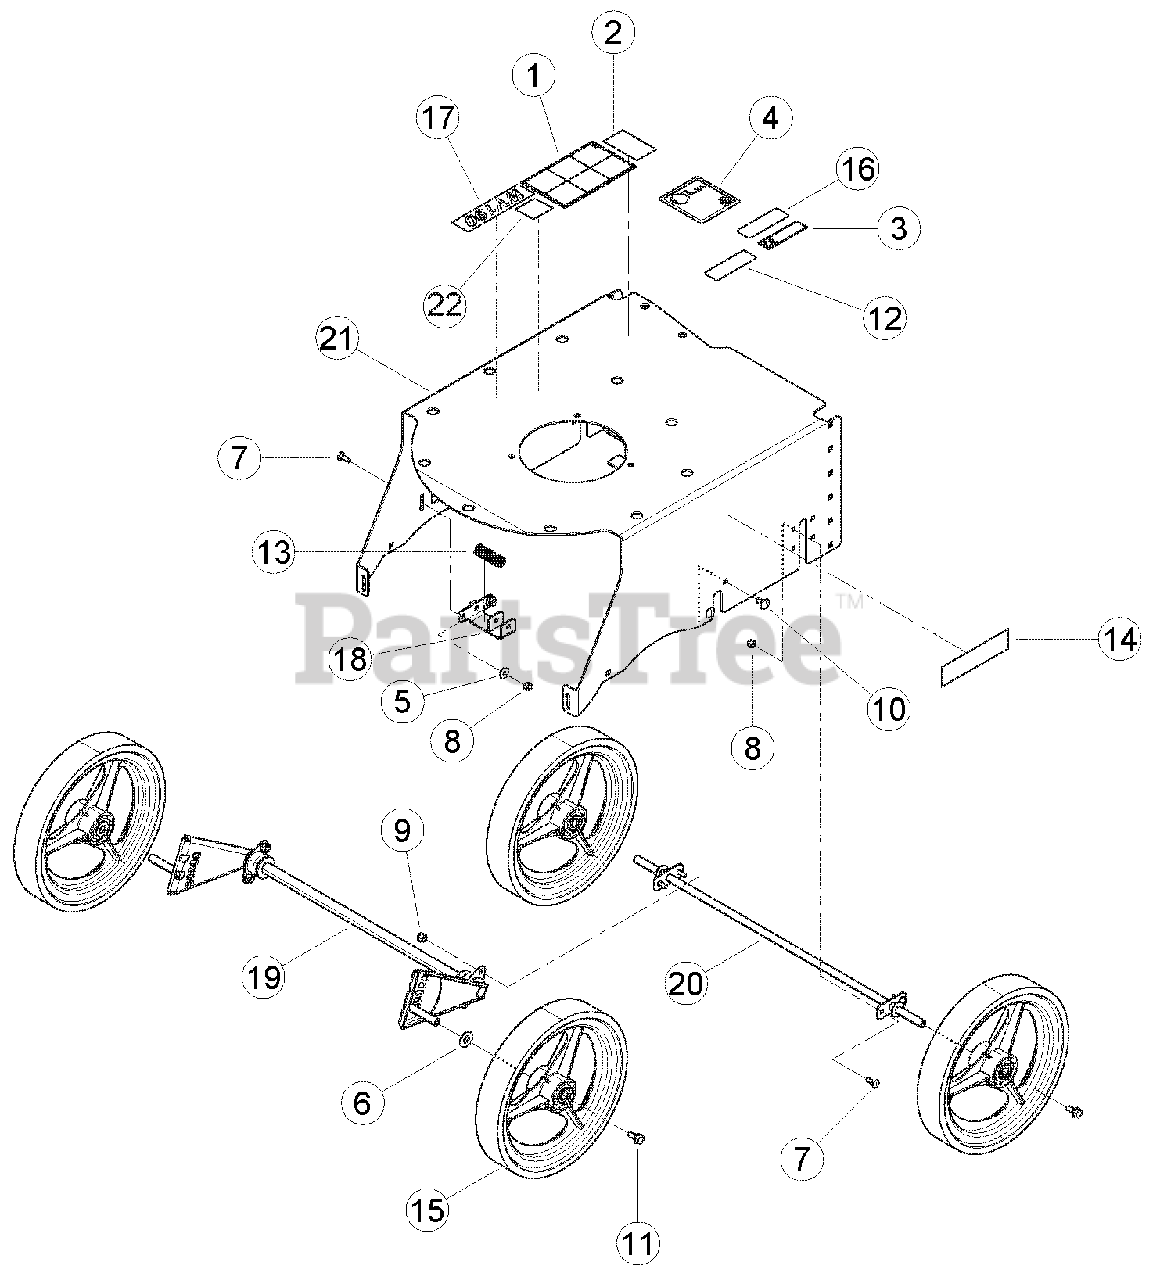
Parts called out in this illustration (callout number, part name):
1	DECAL, OPERATING INSTRUCTIONS ISO
2	DECAL, DANGER
3	DECAL, 6HP PUSH BEARVAC INFORMATION
4	DECAL, 97 DB
5	WASHER, 1/4 FLAT ZP
6	WASHER, 1/2 SAE FLAT ZP
7	BOLT, 1/4 X 3/4 CRG GR5 ZP
8	NUT, 1/4 NE NYLOCK ZP
9	NUT, 5/16 NE NYLOCK ZP
10	BOLT, 5/16 X 5/8 CRG GR5 ZP
11	BOLT, 5/16-18 X 1/2 GR5 HH SER/FLN
12	DECAL, SERIAL NUMBER
13	SPRING, LC-072J065 COMPRESSION
14	DECAL, ECHO BEARCAT
15	WHEEL ASSEMBLY, BEARVAC PUSH
16	DECAL, ATLANTIC BRIDGE LTD INFO
17	DECAL, MODEL WV190
18	WELDMENT, BEARVAC HEIGHT ADJUST
19	WELDMENT, AXLE PIVOT
20	WELDMENT, AXLE BEARVAC PUSH
21	SUPPORT, BEARVAC FRAME
22	DECAL, QR CODE
